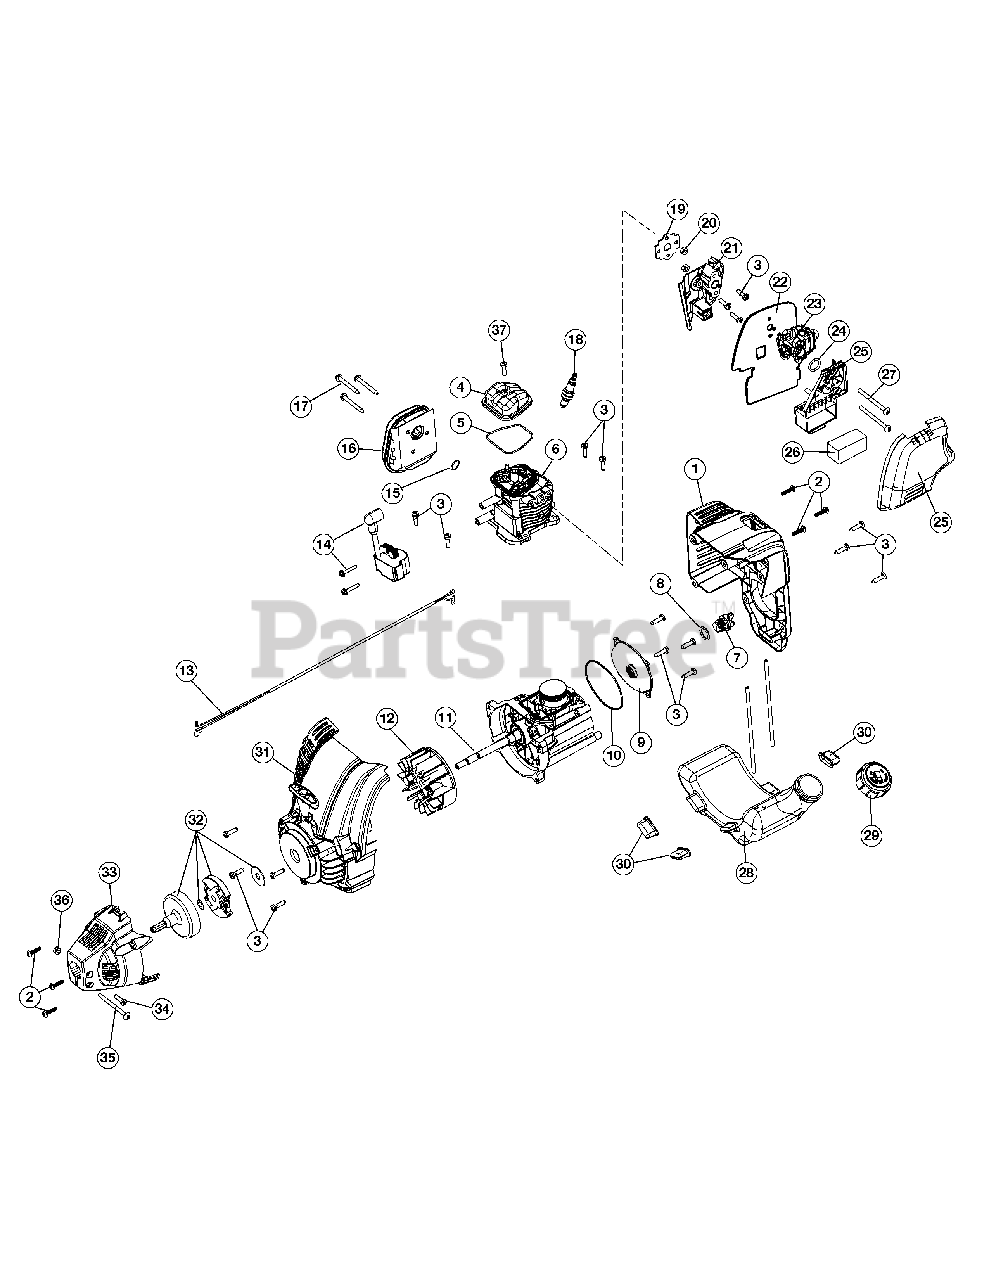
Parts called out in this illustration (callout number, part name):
1	Engine Cover Assembly (Incl. 2 & 3)
2	Cover Screw
3	Screw
4	Rocker Cover
5	Rocker Cover O-Ring
6	Cylinder Assembly (Incl. 3 & 5)
7	Oil Plug (Incl. 8)
8	Oil Plug O-Ring
9	Crankcase Cover
10	Crankcase Cover O-ring
11	Crankcase Assembly (Incl. 10)
12	Flywheel Assembly
13	Lead Wires
14	Module Assembly
15	Muffler Gasket
16	Muffler Assembly (Incl. 15 & 17)
17	Muffler Screw
18	Spark Plug
19	Insulator Gasket
22	Carburetor Gasket
23	Carburetor
25	Air Cleaner Cover Assembly (Incl. 26)
26	Air Filter
28	Fuel Tank Assembly w/Fuel Lines (Incl. 29)
30	Fuel Tank Pads
31	Starter Housing Assembly (Incl. 3)
32	Clutch Assembly
33	Clutch Cover (Incl. 2)
34	Anti-Rotation Screw
35	Clamp Screw
37	Rocker Cover Screw
